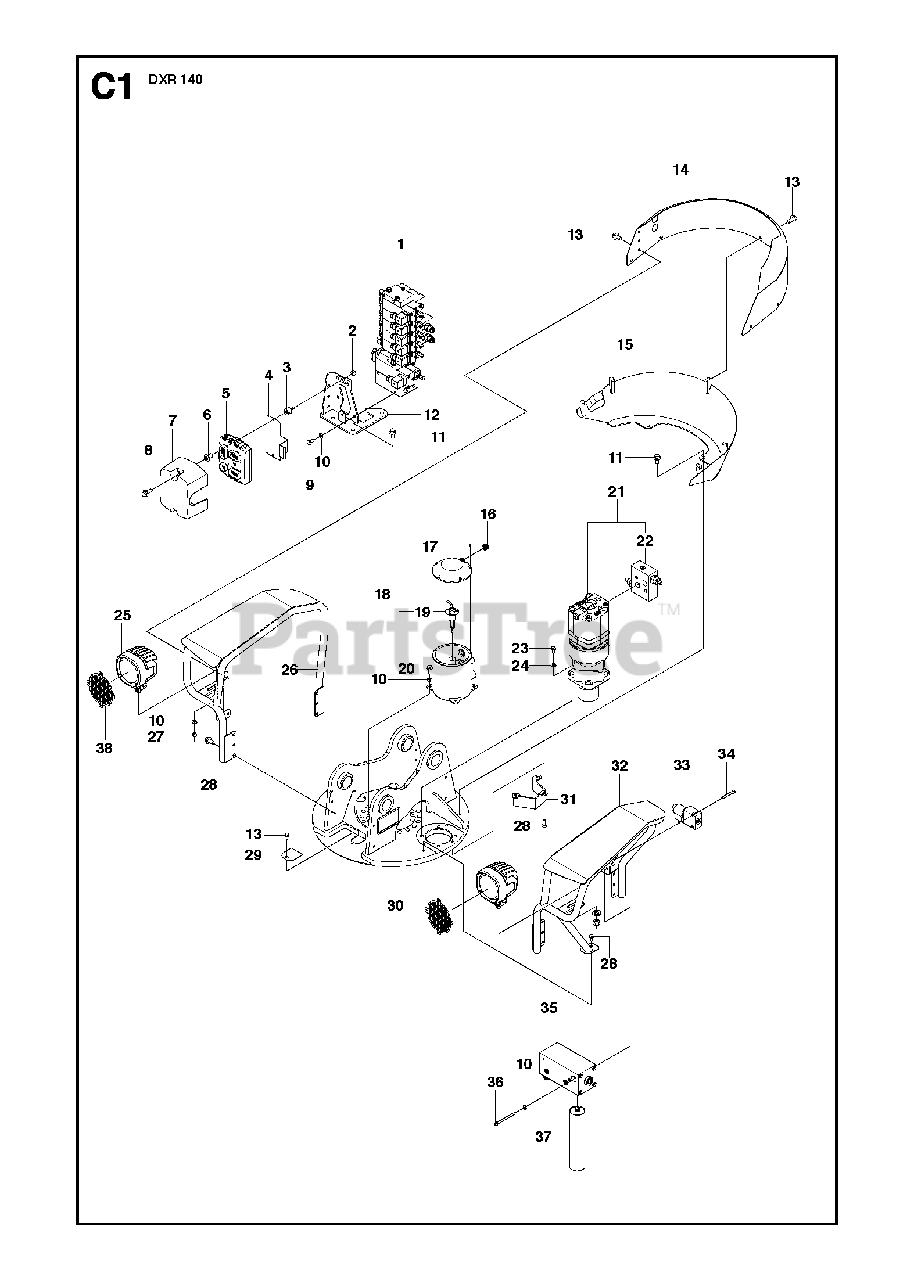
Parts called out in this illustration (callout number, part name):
10	WASHER
34	SCREW EHHFM
38	LENSFor old work light, 573 96 49-01
38	LENSFor new work light, 588 12 61-01
